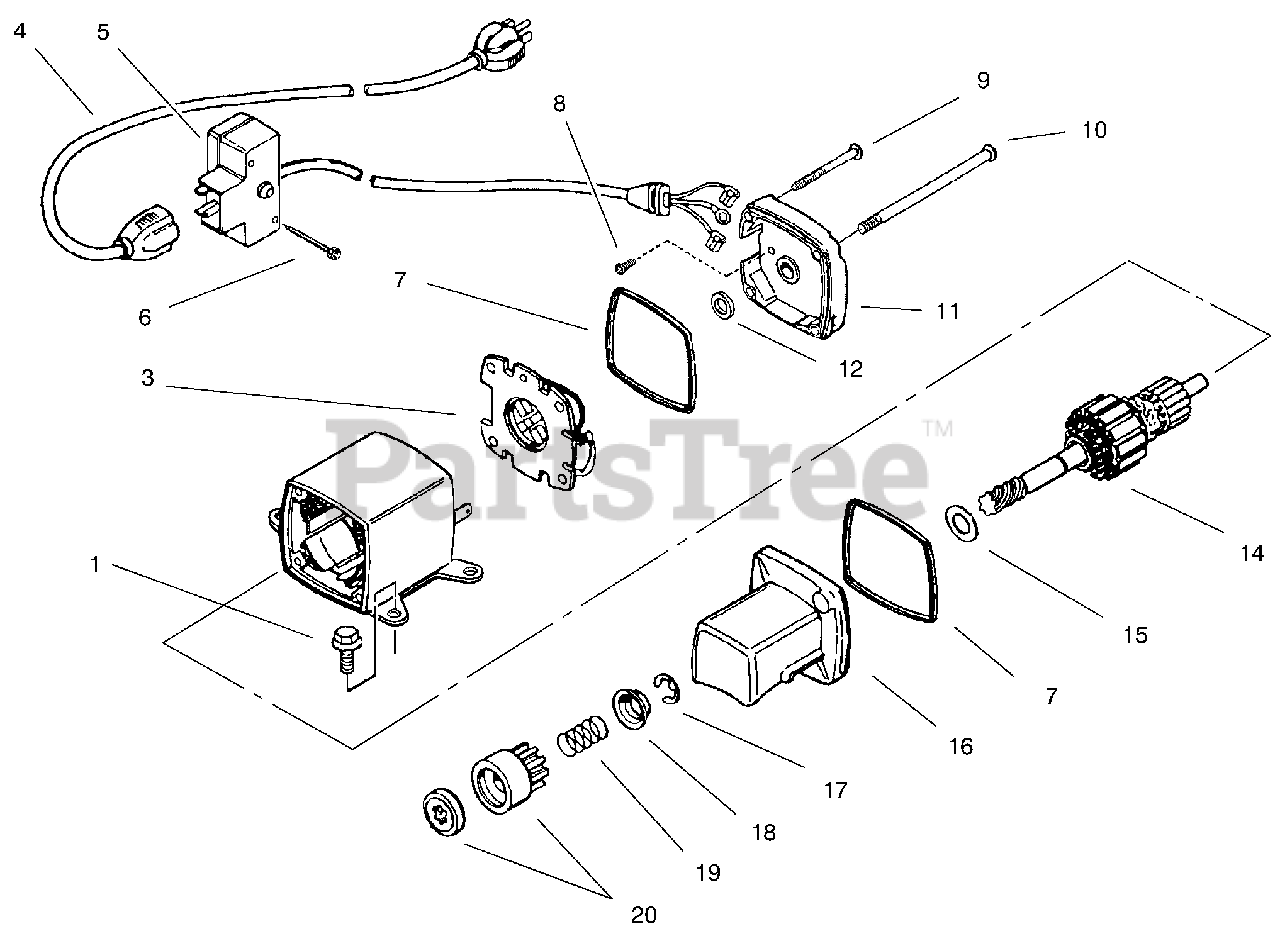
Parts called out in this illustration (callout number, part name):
1	Screw-Torx
3	Brush & Spring Card Asm
4	Cord-Extension
5	Switch Box Asm (Incl. Ref. # 6)
7	"O'Ring
8	Screw-Ground
9	Scerw-Ground
10	Bolt-Case
11	Cap-Commutator End Asm (Incl. Ref. #7)
12	Washer-Thrust
14	Armature
15	Washer-Thrust
16	Cap-Drive End (Incl. Ref.# 7)
17	Ring-Retainer
18	Retainer-Spring
19	Spring-Anti Drift
20	Nut & Gear
